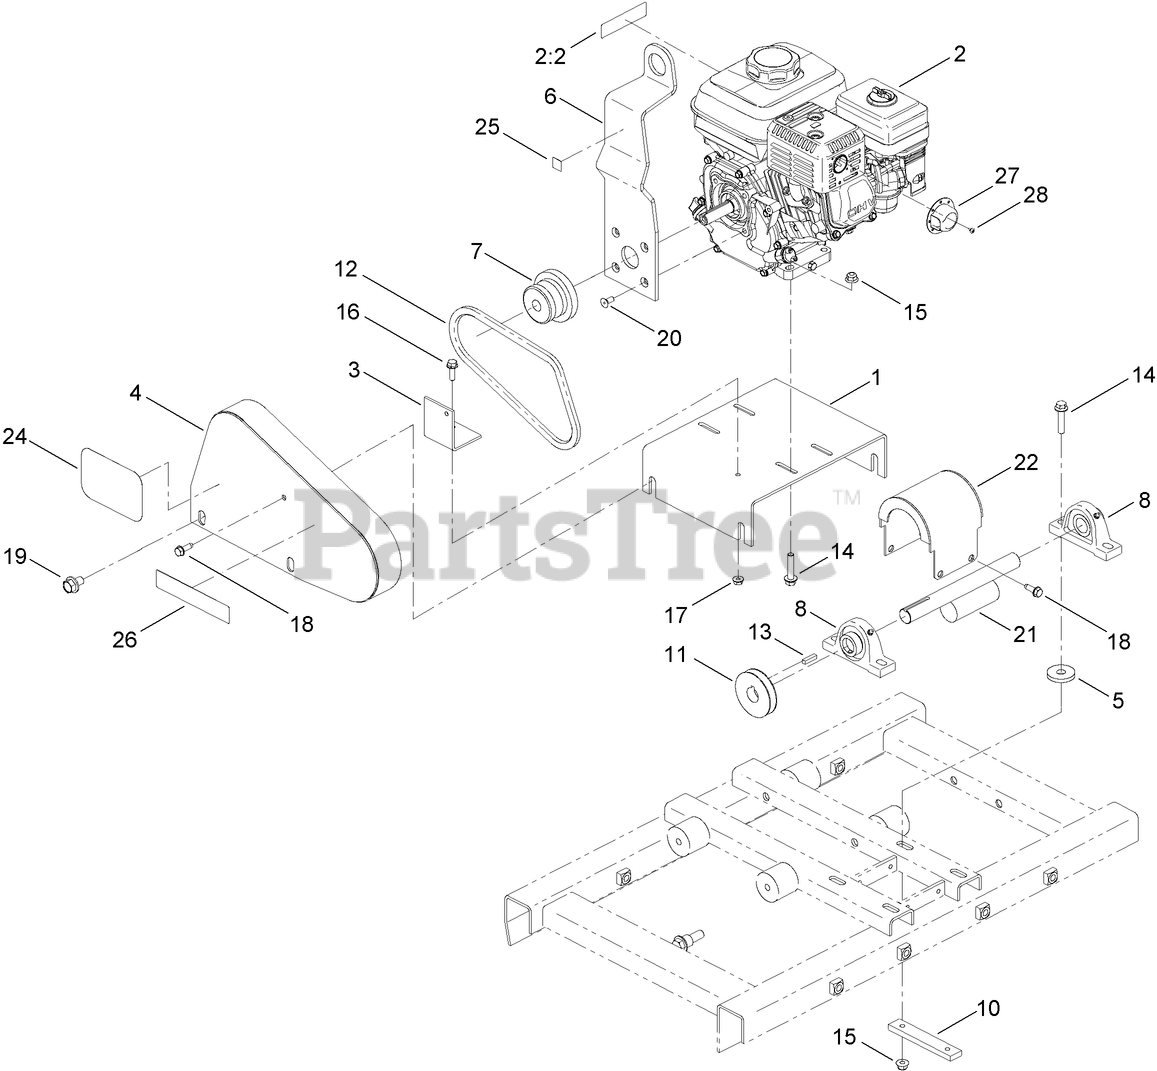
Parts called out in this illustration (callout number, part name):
1	BASE-MOTOR, SCREED
2	ENGINE-HONDA, GX160
2:2	DECAL-ARRESTER, SPARK
3	BRACKET-GUARD, BELT
4	GUARD-BELT
5	WASHER-FLAT
6	PLATE-EYE, LIFT
7	CLUTCH
8	BEARING-BLOCK, PILLOW
10	NUT-PLATE
11	SHEAVE
12	BELT-V
14	SCREW-HHF
15	NUT-HF, NI
16	SCREW-HHF
17	NUT-FLANGE
18	SCREW-HWHTF
19	SCREW-HHF
20	SCREW
21	ECCENTRIC
22	GUARD-ECCENTRIC
25	DECAL-POINT, LIFT
26	DECAL-VS-800
27	DEFLECTOR
28	SCREW-PPHTF
